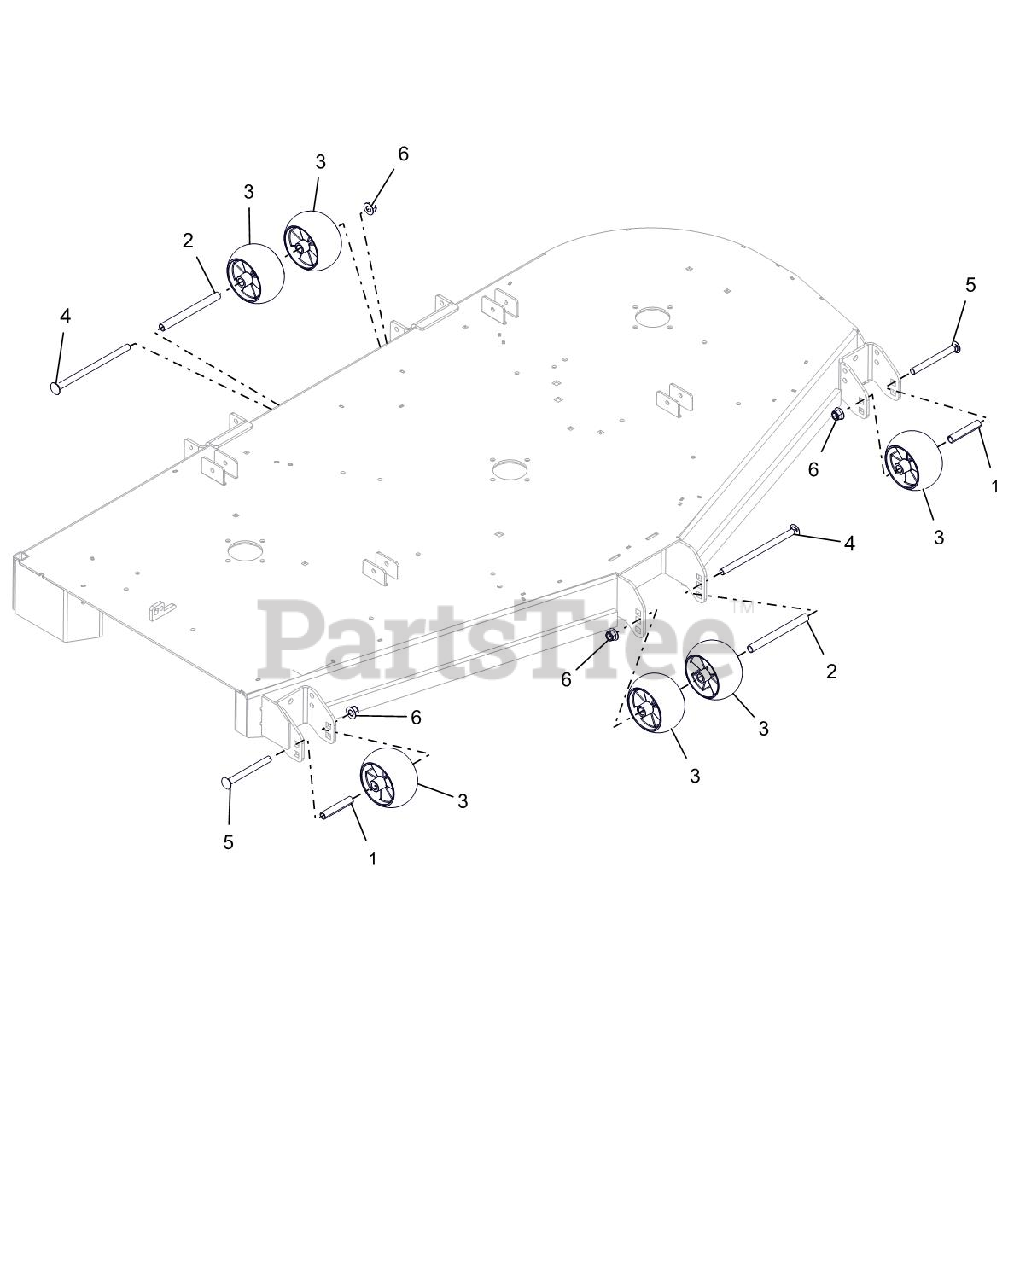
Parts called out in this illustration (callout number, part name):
1	SPACER, .510X.625X3.35
2	SPACER, .510X.625X6.50
3	ANTI-SCALP WHEEL - 5X3 CTR
4	@BLT-RDHDSQNK .50-13X8.50 G5YZ
5	BLT-RDHDSQNK .50-13X5.00 GR5YZ
6	@NUT-LK-NYL-FLG .50-13 YWZC
